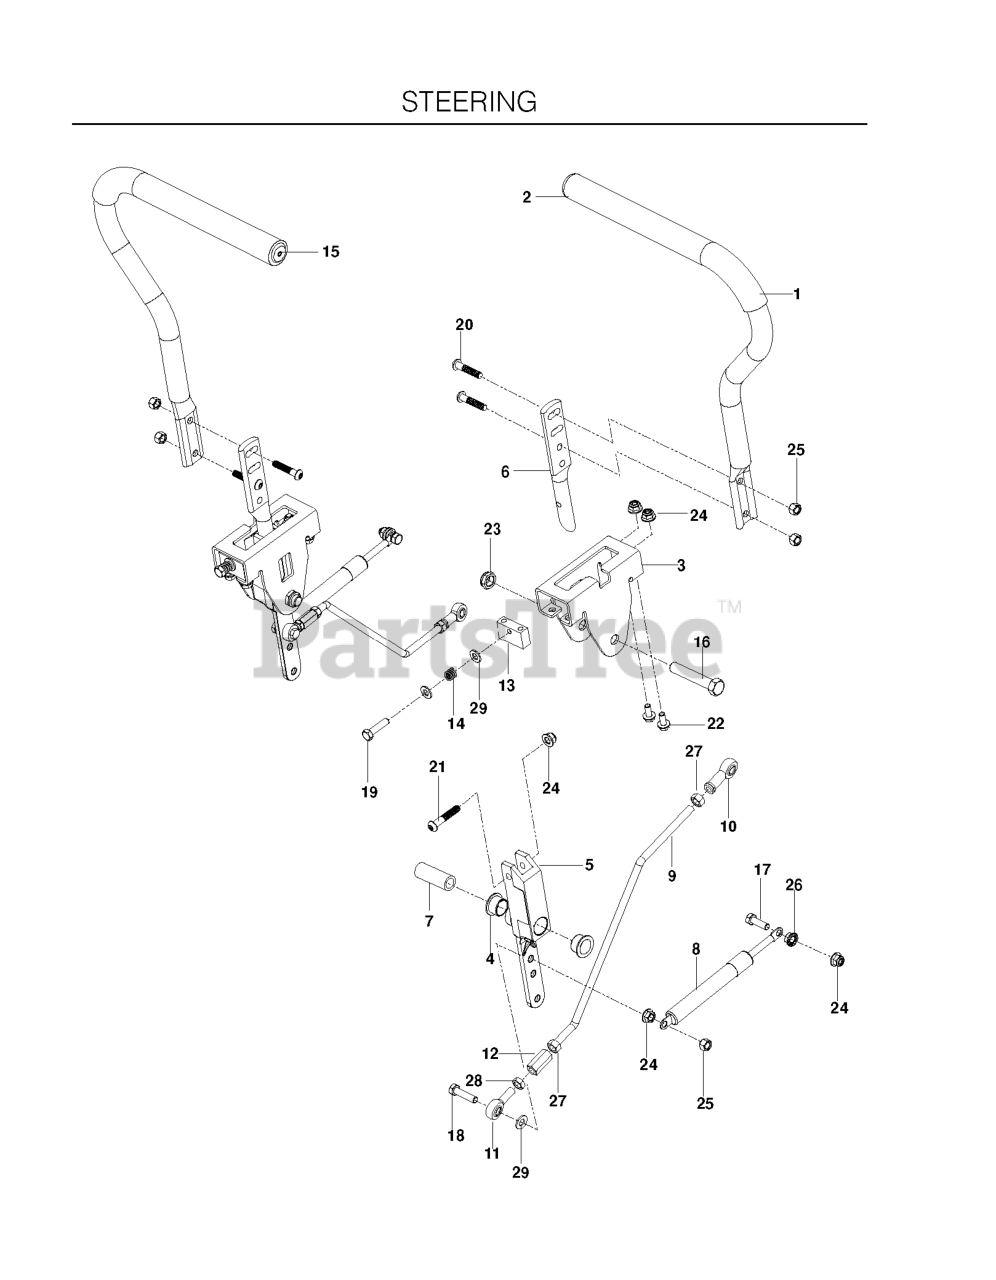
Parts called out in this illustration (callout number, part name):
1	LEVER ASSEMBLY
2	GRIP, FOAM (GROUND) 15
3	BRACKET, CONTROL
4	BEARING, FLANGE
5	LEVER CONTROL PIVOT
6	LEVER.HANDLE MOUNT
7	SPACER, PIVOT CONTROL
9	ROD, MOTION CONTROL
10	RH ROD END
11	RP.ROD.END.LH
12	ROD END COUPLER
13	BLOCK.TRACKING
15	END PLUG 15/16 (BLACK)
16	HCS 1/2C X 2 3/4
17	HCS 5/16C X 1
18	HCS 5/16-18X1-3/4 TPBLT
19	CAPSCREW 5/16 X 1/1/2 HEX HEAD
20	SCREW 5/16-18 X 1 BTN-HD
21	SCREW 5/16-18 X 1 3/4 BTN-HD
22	HHFS 5/16-18 X 3/4
23	NUT 1/2-13 HEX JM NYL
24	5/16-18 NYLOC FLANGE NUT
25	NUT 5/16 NYLOC
26	NUT 5/16C WHIZ
28	NUT 5/16F LEFTHAND
29	FLAT WASHER 5/16 SAE
